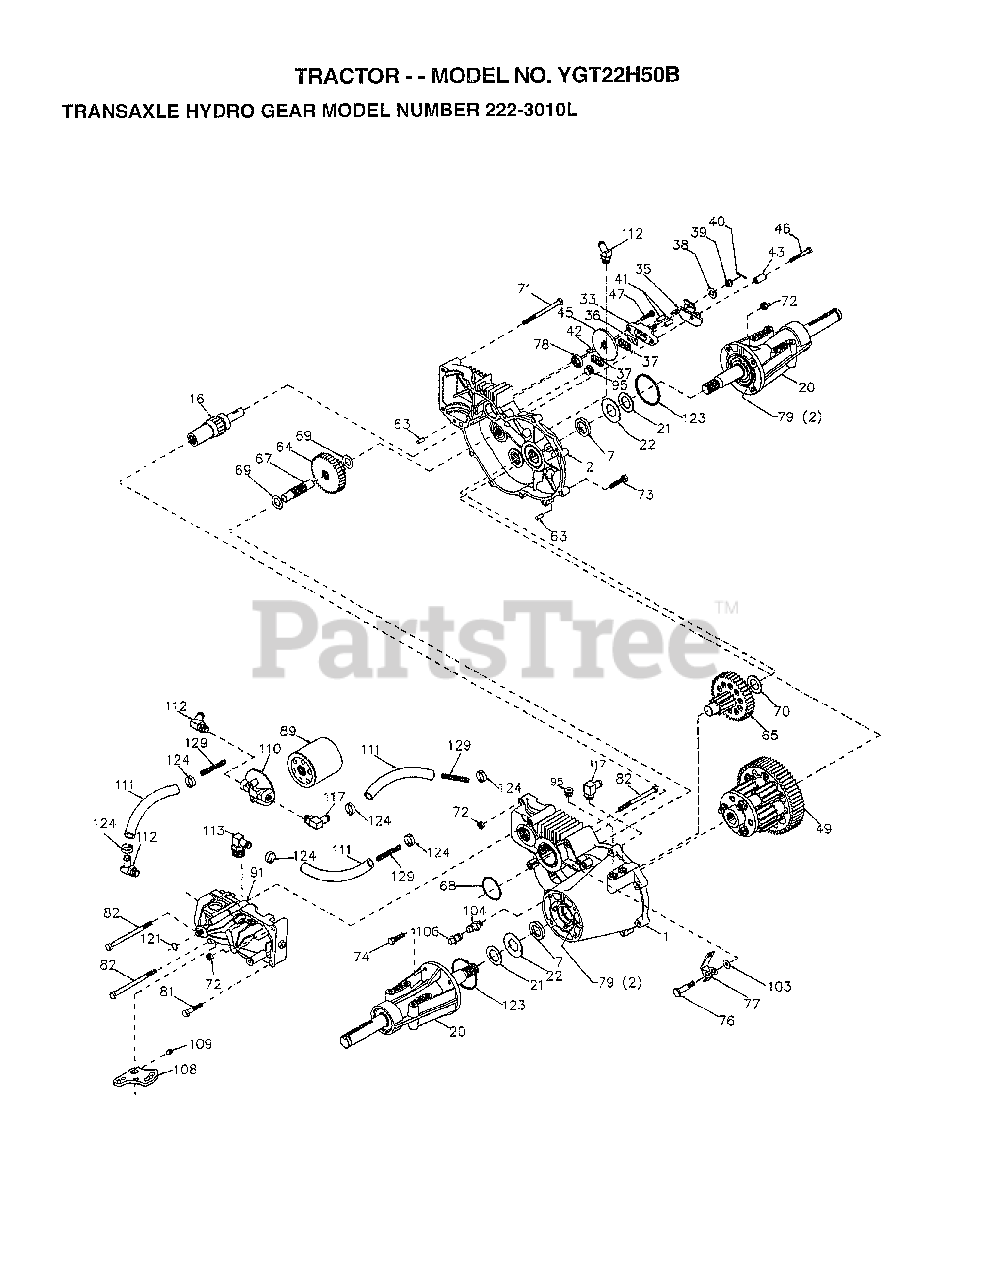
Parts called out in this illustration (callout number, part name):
1	HOUSING LH 70086
2	HOUSING RH 70088
7	SEAL.OIL.44782.HY
16	SHAFT BRAKE 62877
20	AXLE MTG 70087
21	WASHER 44805
22	WASHER 44806
33	YOKE.BRAKE.62589
35	ARM BRAKE 50214
36	PUCK PLATE 44134
37	PUCK BRAKE 44132
38	WASHER HYD 44130
41	PIN BRAKE 44127
42	KEY HI PRO 44143
43	SPACER 50259
45	DISC BRAKE 44090
46	BOLT 1/4-20 44276
47	BOLT 1/4-20 44433
49	DIFFRENTIAL.70251
63	PIN DOWL 44757
64	GEAR.14-38.44776
65	PINION DRIV 70051
67	SHAFT-44779
68	O RING 44781
69	WASHER 44795
70	WASHER 44794
71	BOLT 5/16 44827
72	LOCKNUT.43064
73	BOLT 5/16 44841
74	SCREW 5/16 45089
76	BOLT SHOULD 44785
77	ARM FREEWHL 44786
78	SEAL.OIL.44761
81	BOLT 5/16 43084
82	BOLT 5/16 44820
89	FILTER SPIN 50037
91	PUMP.BDU-10L-122
95	PLUG.9005110-5600
96	FITTING.SAE.50257
103	WASHER.50169
104	CAP.VENT.70109
106	O-RING.ASM.70110
108	ARM.CONTROL.45007
109	SCREW.SET.50018.
110	FILTER.HEAD.50207
111	HOSE.50632
112	FITTING.SAE.50604
113	FITTING.SAE.50592
117	FITTING.SAE.50589
123	O-RING.50405
124	CLAMP.50590
129	SPRING.LONG.50667
